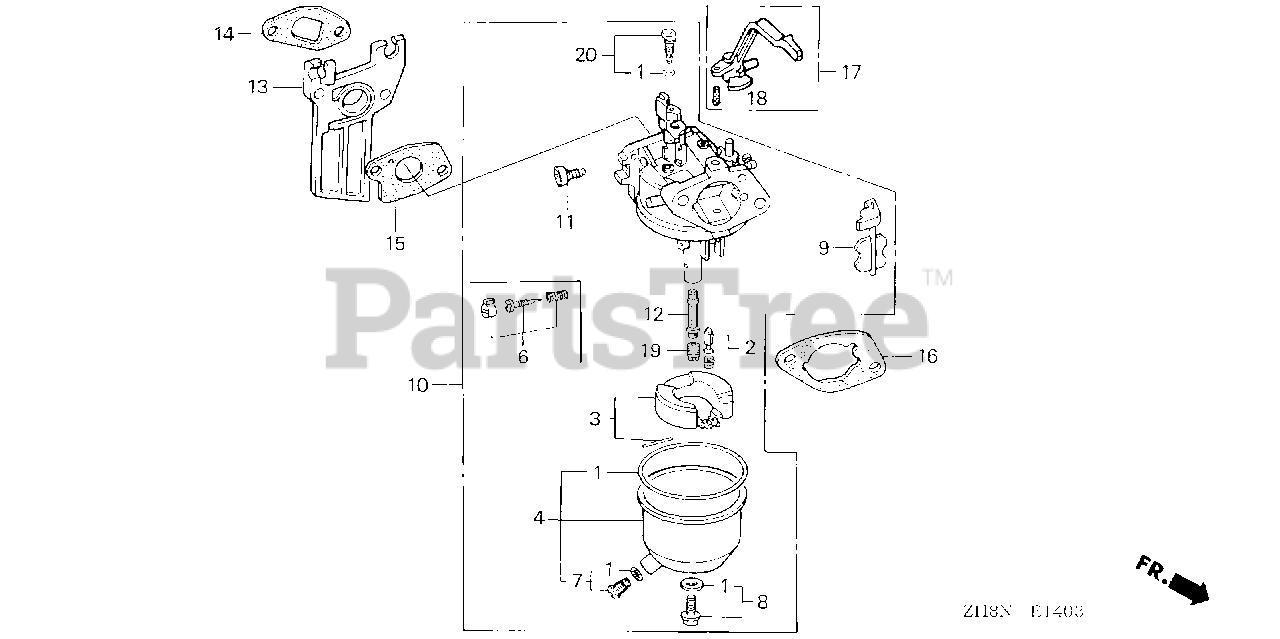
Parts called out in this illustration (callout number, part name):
1	GASKET SET
2	VALVE SET, FLOAT
3	FLOAT SET
4	CHAMBER SET, FLOAT
6	SCREW SET
7	SCREW SET, DRAIN
8	SCREW SET B
9	CHOKE SET
10	CARBURETOR ASSY. (BE67A B)
11	SCREW, THROTTLE STOP
12	NOZZLE, MAIN
13	INSULATOR, CARBURETOR
14	GASKET, INSULATOR
15	GASKET, CARBURETOR
16	GASKET, AIR CLEANER
17	LEVER, CHOKE
18	PIN, SPRING (2X12)
19	JET, MAIN (#70)
19	JET, MAIN (#72)
19	JET, MAIN (#75)
20	JET SET, PILOT (#35)
